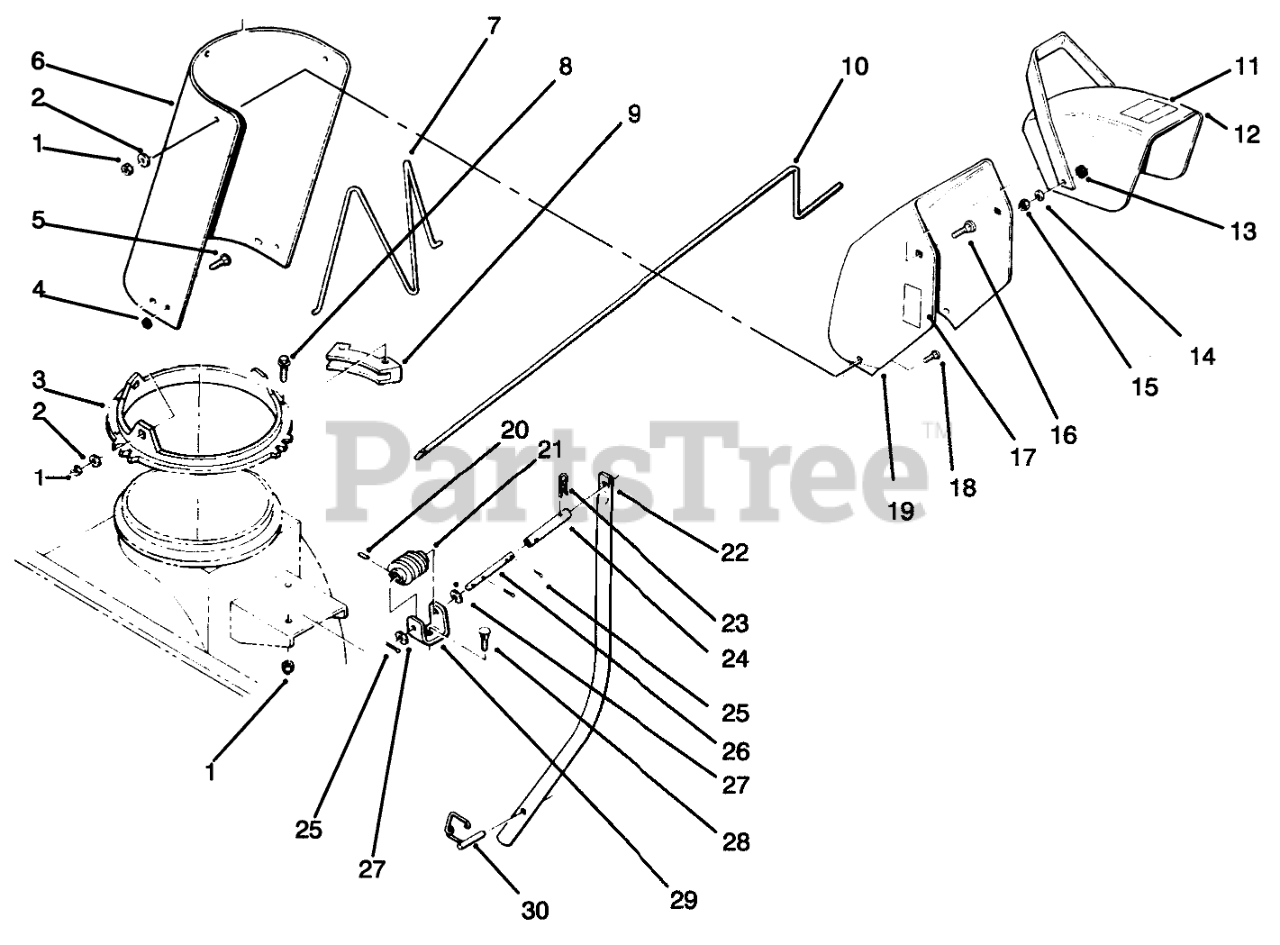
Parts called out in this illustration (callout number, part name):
1	NUT-LOCK, NI
2	WASHER-PLAIN
3	Screw
4	NUT-PUSH
5	SCREW-HH
6	Chute-Extender
7	WIRE-CHUTE
8	SCREW-SPECIAL
9	RETAINER-CHUTE
10	ROD-CHUTE CONTROL
11	Decal-Danger
12	Deflector Assembly (Incl. Ref. #11)
13	WASHER-RUBBER
14	WASHER-BELLEVILLE
15	NUT-LOCK, NI
16	BOLT-CARR
17	Decal-Danger
18	CARRIAGE BOLT -4
19	Chute-Upper Discharge (Incl. Ref. #17)
20	Pin-Roll
21	GEAR-WORM, CHUTE
22	TUBE-CRANK SUPPOR R
23	Hairpin Cotter
24	COUPLING
25	PIN-COTTER
26	ROD-LOWER CHUTE CONT
27	WASHER-FLAT
28	BOLT-CARR
29	WORM BRKT B
30	LOCKING PIN ASM
